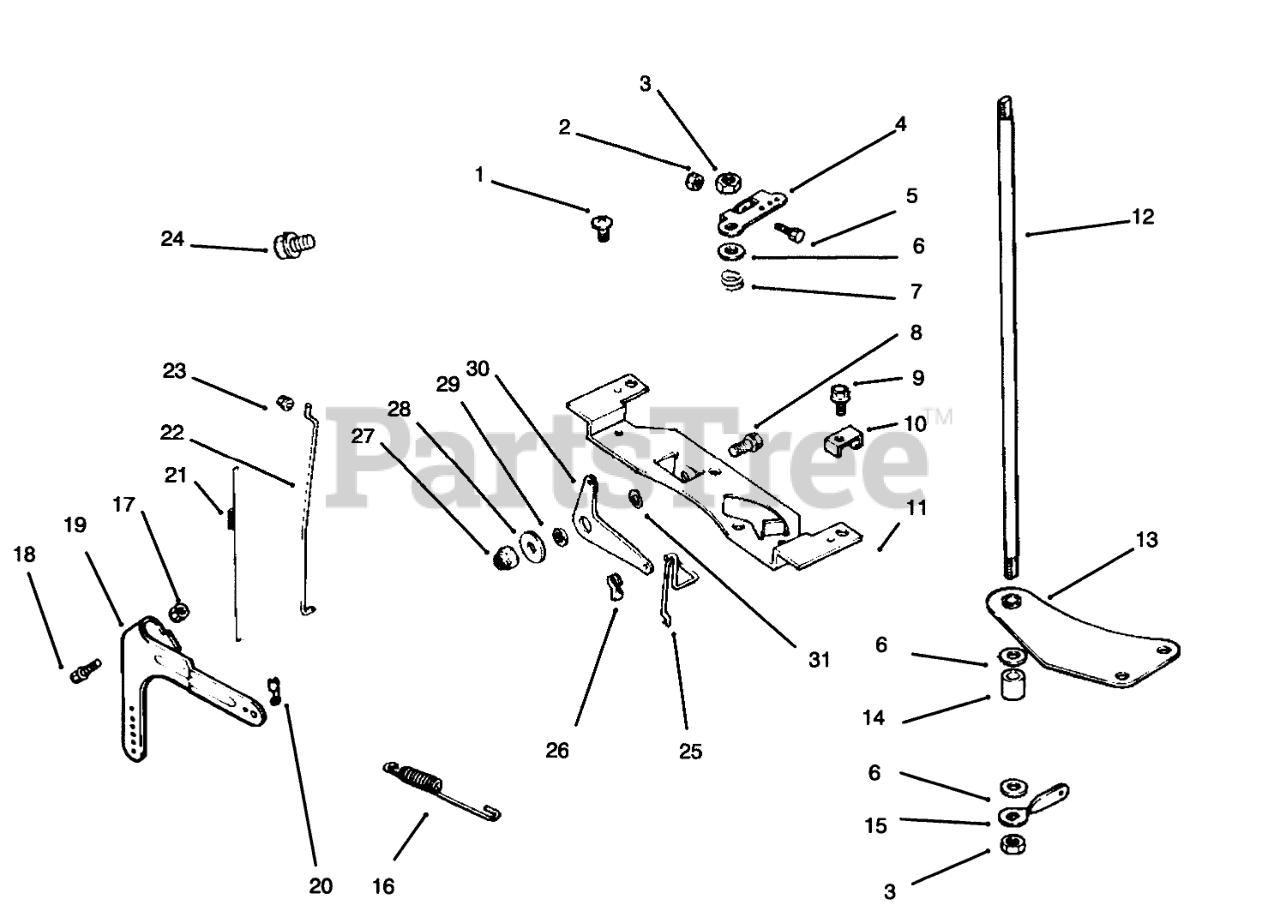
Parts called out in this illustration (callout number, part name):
1	Screw
2	Nut
3	Nut
4	Lever-Throttle Control
5	Screw
6	Washer
7	Spring-Throttle Shaft
8	Screw
10	Clamp
11	Bracket-Control
12	Shaft-Throttle
13	Bracket-Throttle Shaft
14	Spacer
15	Lever-Throttle Control
16	Spring-Governor
18	Screw
19	Lever-Govenor
20	Bushing-Linkage
21	Spring-Linkage
22	Linkage-Throttle
23	Bushing-Linkage
24	Screw
25	Linkage-Choke
26	Bushing-Linkage
27	Nut
28	Washer
29	Spacer
30	Lever-Choke
31	Washer
